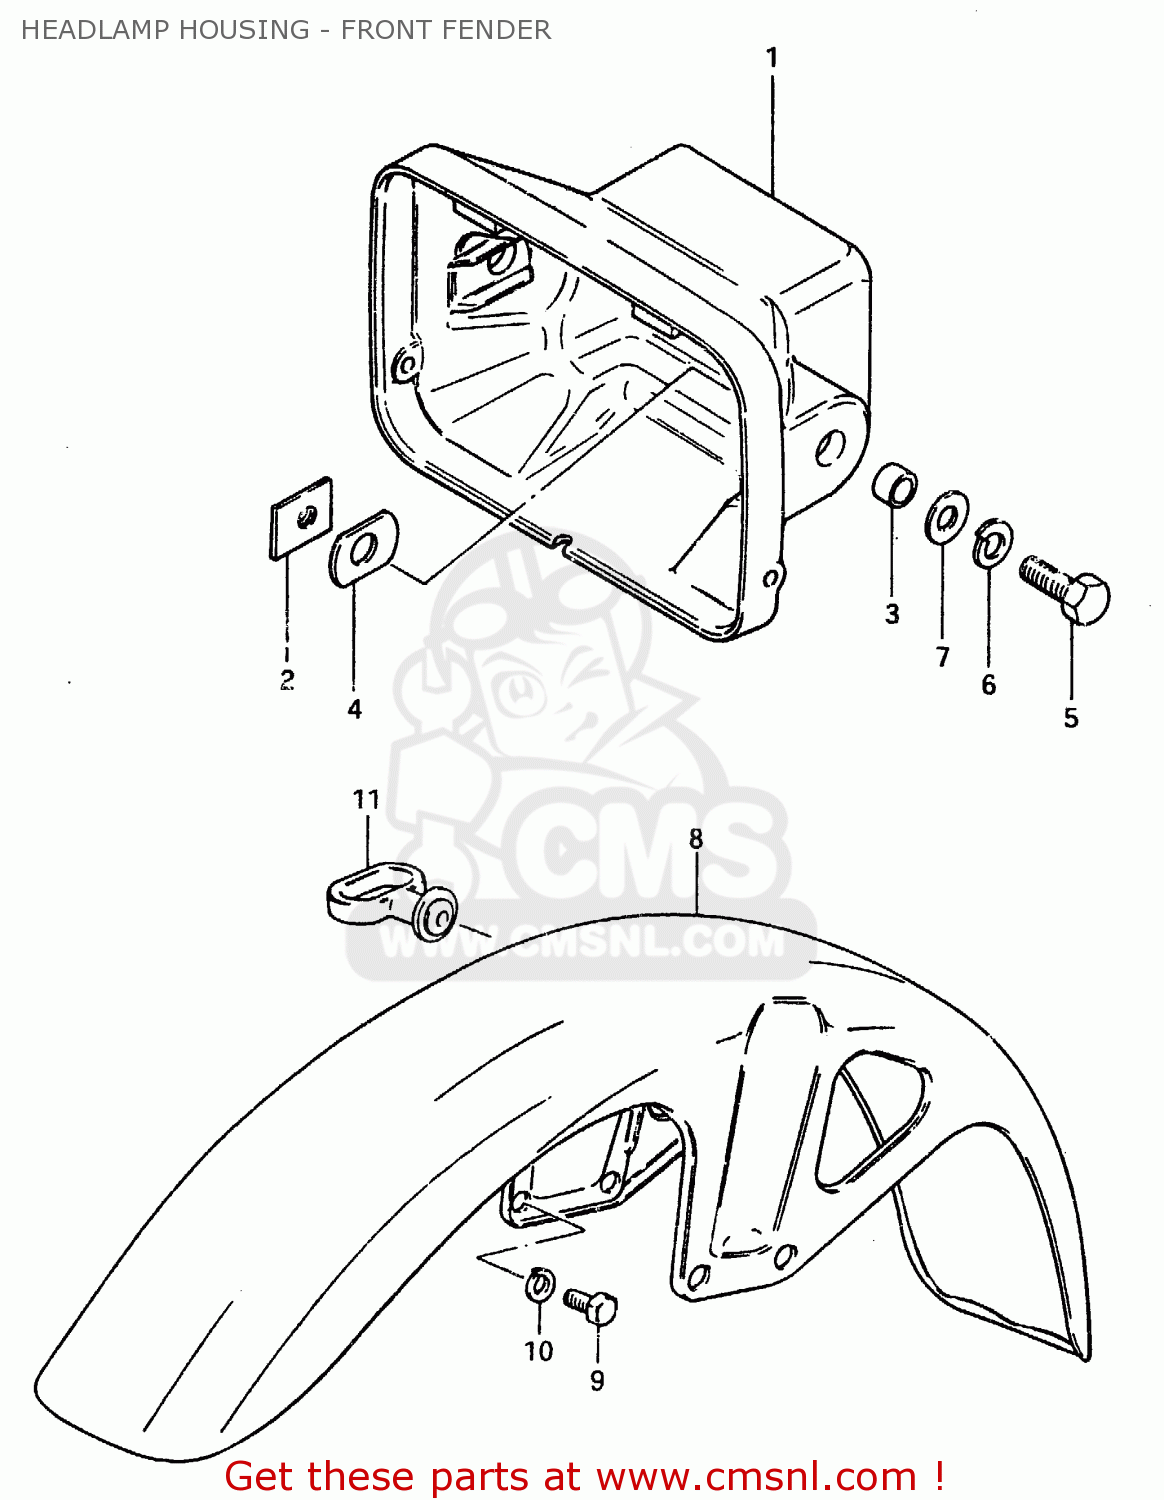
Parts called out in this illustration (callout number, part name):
1	HOUSING, HEADLAMP (BLACK)
2	PLATE,HEADLAMP HOUSING
3	SPACER (8.8X12X7)
4	CUSHION
5	BOLT
6	LOCK WASHER
7	WASHER
8	FENDER, FRONT
9	BOLT
10	LOCK WASHER
11	GUIDE,CABLE
